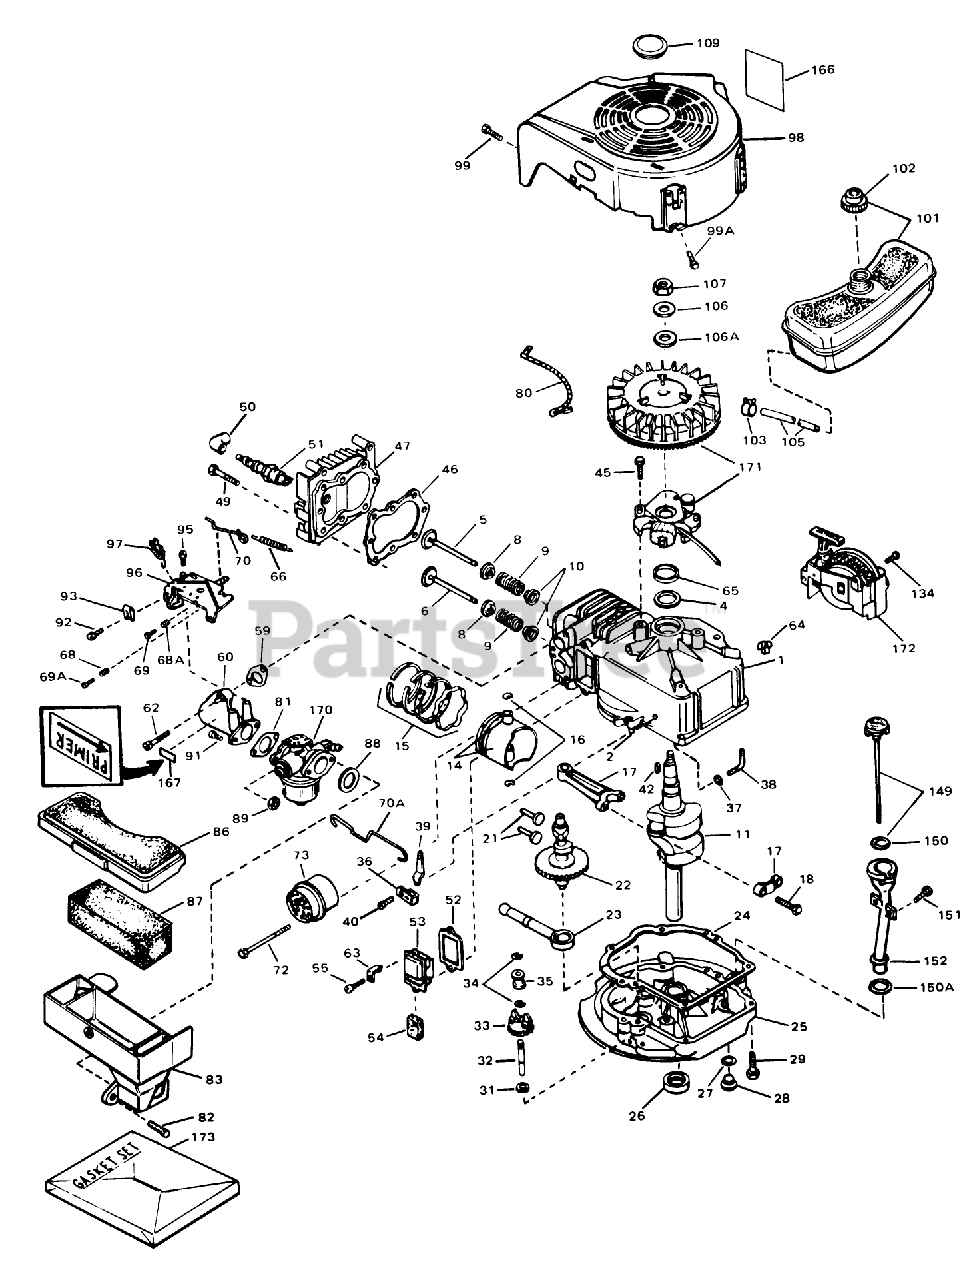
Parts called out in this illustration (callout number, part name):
1	Cylinder Assembly (Incl. Ref. #2 4)
2	Pin-Dowel
4	OIL SEAL
5	Valve, Intake (Incl. Ref. #38, 39 40) (Std.)
5	Valve, Exhaust (1/32" Oversize) (Incl. Nos. 8, 9 10)
6	Valve, Exhaust (Standard) (Incl. Nos. 8, 9 10)
6	Valve, Exhaust (1/32" Oversize) (Incl. Nos. 8, 9 10)
8	Cap-Upper Valve Spring
9	Spring-Valve
10	Cap-Valve, Spring
11	Crankshaft
14	Piston, Pin Ring Assy. (Std.) (Incl. Ref. #15 16)
14	Piston, Pin Ring Assy. (.010 Oversize) (Incl. Ref. #15 16)
14	Piston, Pin Ring Assy. (.020 Oversize) (Incl. Ref. #1516)
15	Piston Ring Set Std.
15	Piston Ring Set .010 O.S.
15	Piston Ring Set .020 O.S.
16	Ring-Retaining, Piston Pin
17	Rod Assy., Connecting (Incl. Ref. #17)
18	Bolt-Rod, Connecting
21	Lifter-Valve
22	Camshaft(Mech.Comp. Release)
23	Oil Pump ASM
24	*26750A Gasket, Mounting Flange
25	Flange Assy., Mounting (Incl. Ref. #26thru 30)
26	Seal Oil
27	*28833 Gasket, Oil Drain Plug
28	Plug Oil Drain
29	Screw (1/4-20 x 1-1/4)
31	Washer-Flat
32	Shaft-Governor
33	Governor Gear ASM
34	Ring-Retaining
35	Spool-Governor
36	Clamp-Lever, Governor
37	Washer-Flat
38	Rod, Governor (Incl. No. 36)
39	Lever, Governor
40	Screw, Hex Washer Hd.
42	Key-Flywheel
45	Screw
46	*29953B Gasket, Cylinder Head
47	2025A67 ADD.ASSEMBL
49	Screw (5/16-18x1-1/2)
50	Cover-Spark Plug
51	Plug, Spark (J17LM or equiv.)
51	Plug, Spark (Champion RCJ-8)
52	*31619 Gasket, Breather
53	Breather Assembly (Incl. Nos. 52 84)
54	Element-Breather
55	Screw
59	*32649 Gasket, Intake Pipe
60	Pipe, Intake
62	Screw (1/4-20 x 1)
63	Retainer Clip
64	51004 GIL ROTARY TI
65	Gasket Stator
66	Spring Governor
68	61709/GIL1515A/95-5
68A	Spring-Compression
69	Screw
69A	Screw
70	2035A67 ADD.ASSEMBL
70A	Link-Throttle
72	Screw
73	Muffler Kit (Incl. Ref. #72)
80	Wire-Ground
81	*26756 Gasket, Carburetor
82	Screw
83	Body, Air Cleaner
86	Cover Air Cleaner
87	Filter-Air Cleaner
88	*34338 Gasket, Air Cleaner
89	Nut and Lock Washer (1/4-28)
92	Screw (10-32 x 3/8)
93	Conduit
95	Screw (10-24 x 9/16)
96	Control Assy.-Remote Speed (Incl. Ref. #69 thru 72 76)
97	Terminal
98	Housing, Blower
99	Screw (10-24 x 9/16)
99A	Screw
101	Tank, Fuel
102	Cap, Fuel
103	Clamp-Line, Fuel
105	Line-Fuel (8.62)
106	Washer-Spring
106A	Washer Flat
107	Hex Nut
109	Plug, Screen
134	Screw (1/2-20x5/8)
149	Dipstick-Oil (Incl. Ref. #112)
150	O-Ring
150A	Gasket
151	Screw (10-32 x 1/2)
152	Tube-Oil Fill
166	Decal-Instruction
167	Decal, Instruction
170	Carbu retor (Incl. Ref. #81)
171	Magneto
172	Starter-Sidemount
173	Gasket Set
